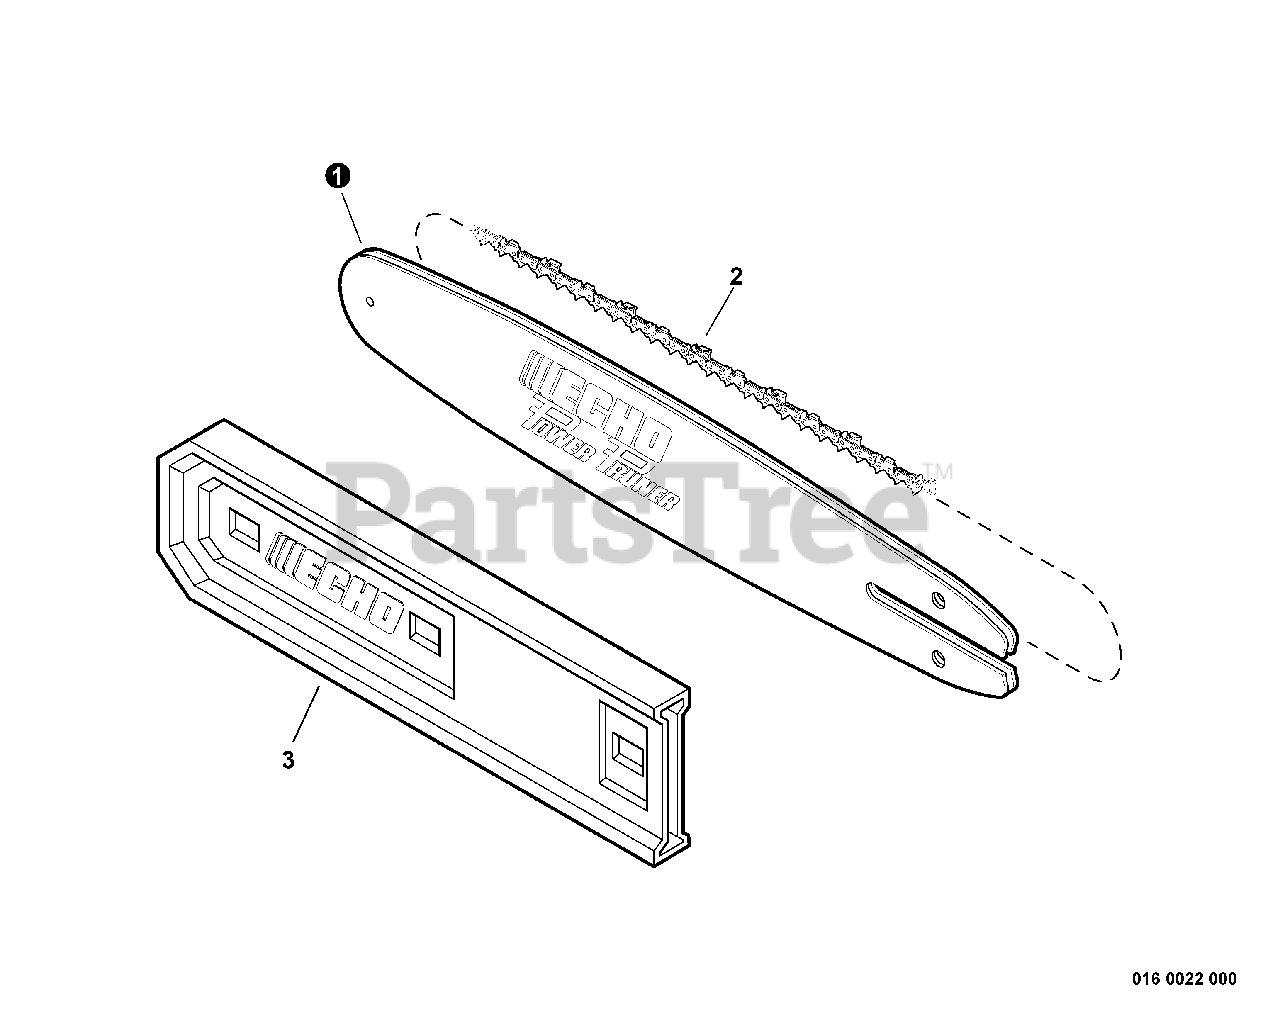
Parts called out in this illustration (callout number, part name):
1	GUIDE BAR, 10" 0.050" GA
2	SAW CHAIN 10" 0.050" GA
3	SCABBARD 10"
